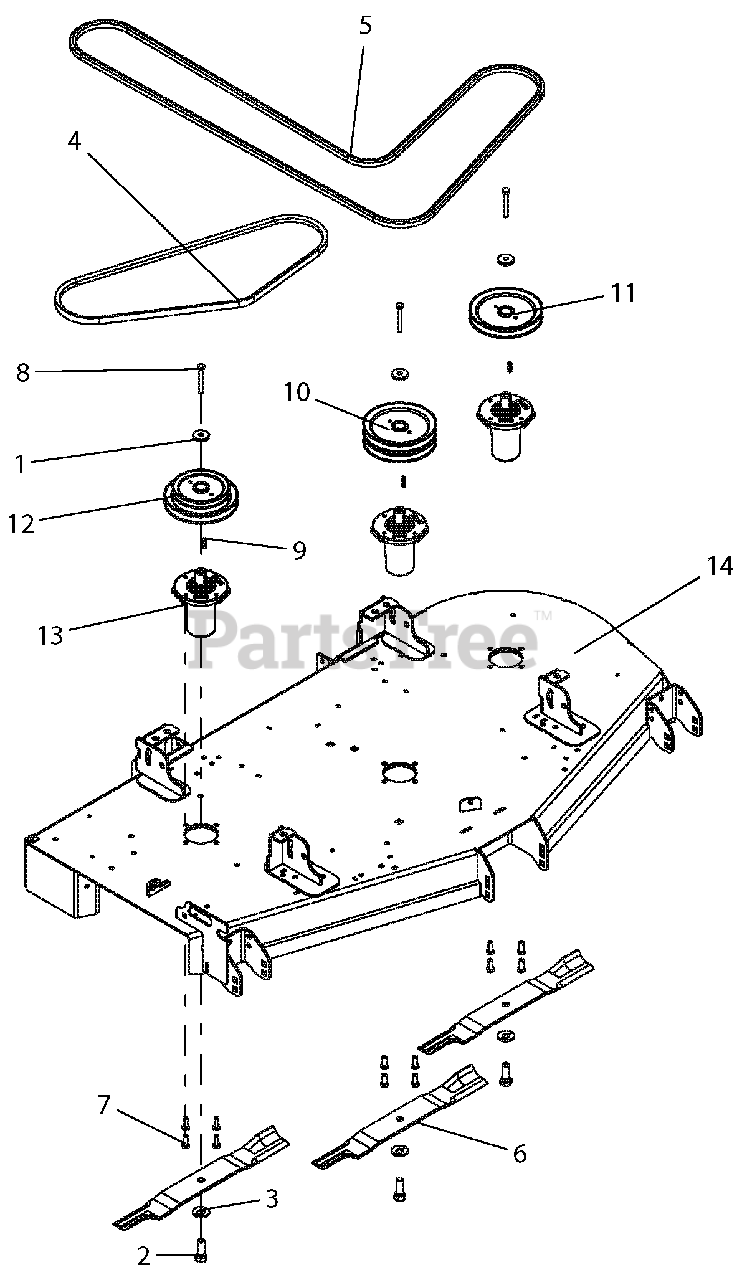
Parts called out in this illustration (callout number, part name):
1	RETAINER, SHEAVE SPINDLE
2	BLT, HEX .62-18X1.75 GR8 YWZC
3	WSHR, BLVL .63X1.625X.14
4	BELT, B 63.00 RAW COGGED
5	BELT, BB 118.00 WRAPPED HEX
6	BLADE, MOWER 60"
7	BLT-HEX .38-16X1.00 GR5 YWZC EP30
8	BLT-HEX .38-16X2.75 GR8 YWZC
9	KEY-SQ .250X.250X1.00 RC 40-50
10	PULLEY, DOUBLE 1"ID X 6.75"OD-BLACK
11	PULLEY, V-1" ID X 6.75" OD-BLACK
12	PULLEY, DOUBLE -1" ID X 6.75" & 5.25" OD
13	SERVICE, ASM SPINDLE- DUCTILE
14	WLDMT, 60" SIDE DISCH DECK
